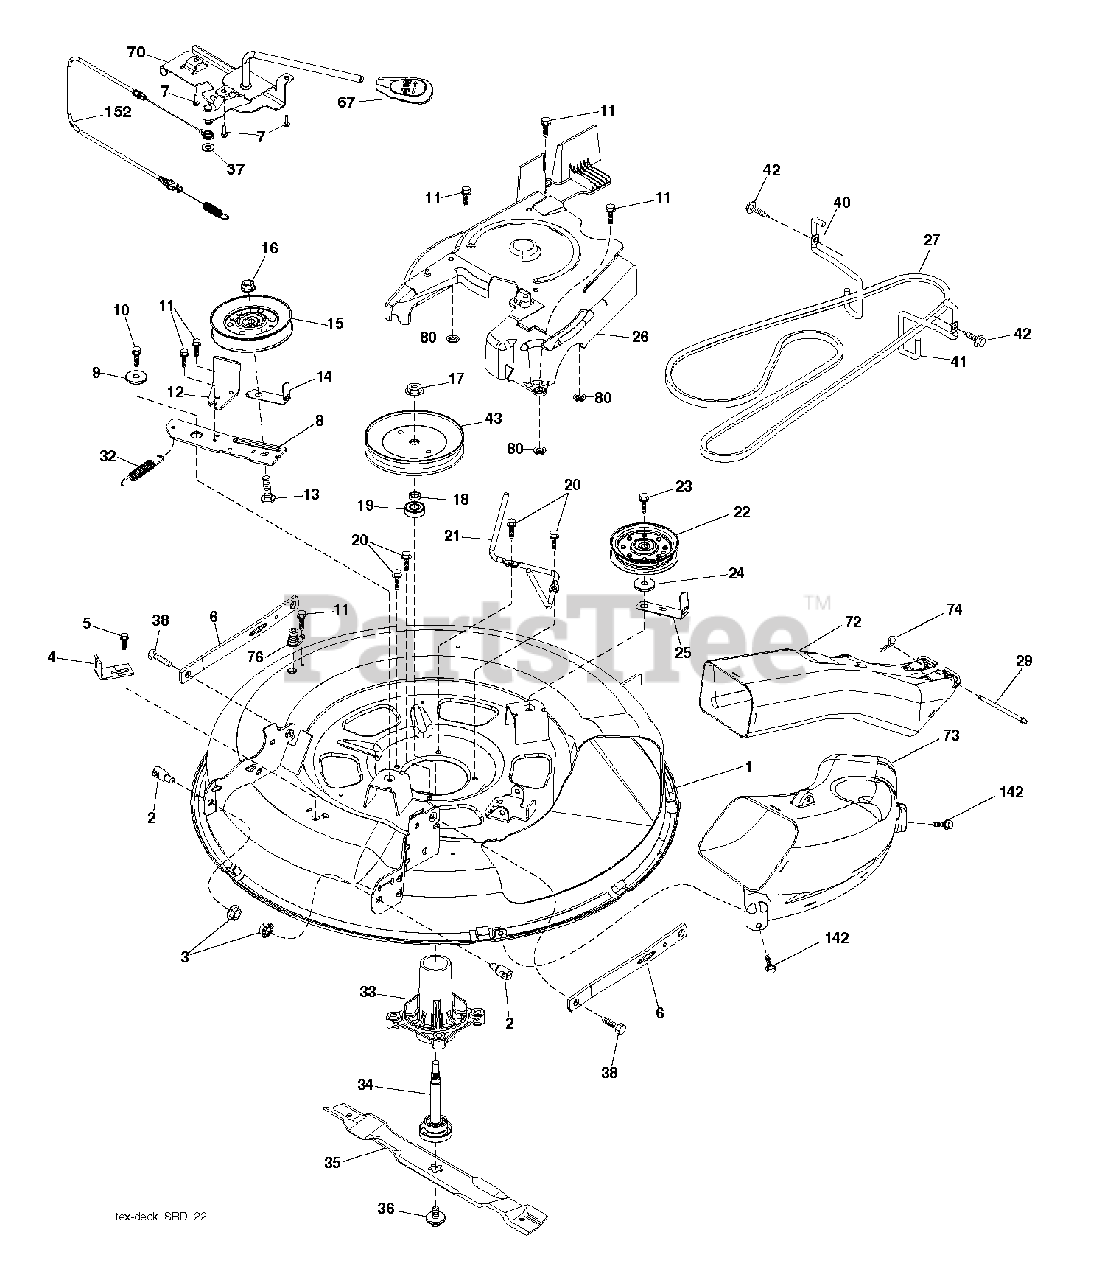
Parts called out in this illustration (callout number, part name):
1	DECK.WELDMENT.30"SRD.BLACK
2	STUD.FASTNER.W/ANTI-ROTATE
3	NUT LOCK HEX FLANGE 5/16-18
4	Clutch Cable Bracket
5	BOLT.5/16HEX.WHS.HD
6	ARMS.SUSP.MOWER.REAR.SRD
7	SCREW.#10 X 0.750.BOS THREAD
8	ARM.IDLER.30"SRD
9	SPACER.RETAINER
10	SCREW 3/8-16X1
11	SCREW.1/4-20X5/8
12	ARM BRAKE MOWER RH
13	BOLT.3/8-16X1.50
14	KEEPER, BELT IDLER
15	PULLEY.IDLER.4.25
16	NUT LOCK FLG 3/8-16 UNC
17	NUT.FLANGE.LOCK.TOP
18	WASHER.SPACER.MANDREL
20	SCREW, WASHER HEAD
21	KEEPER.BELT.MANDREL.30"
22	PULLEY.IDLER.FLAT.UNPLATED
23	SCREW LT
25	KEEPER.BELT.30"SRD
26	Mandrel Cover, 30" Deck
27	V-BELT.DRIVE.MOWER.30"
29	PIN.HINGE.30".SRD
32	SPRING RETURN
33	HOUSING MANDREL
34	SHAFT.ASM.MDRL.N/GREASE.38
35	BLADE.MOWER.BAGGING.30"
36	BOLT.WASHER.ASM.7/16-2
38	BOLT.SHOULDER
40	KEEPER.BELT.ENGINE.LH.LT.SRD
41	KEEPER.BELT.ENGINE.RH.LT.SRD
42	SCREW, 3/8-16X3/4
43	PULLEY, MANDREL 6.5 PD
67	HANDLE.CLUTCH.CABLE.LT
70	CLUTCH.ASM.MANUAL.LT.TEX
72	CHUTE.UPPER.SRD.30R
73	Lower Chute, SRD 30R"
74	RETAINER-SPRNG RB
142	SCREW, 3/8-16X3/4
152	CABLE.CLUTCH.MANUAL.
